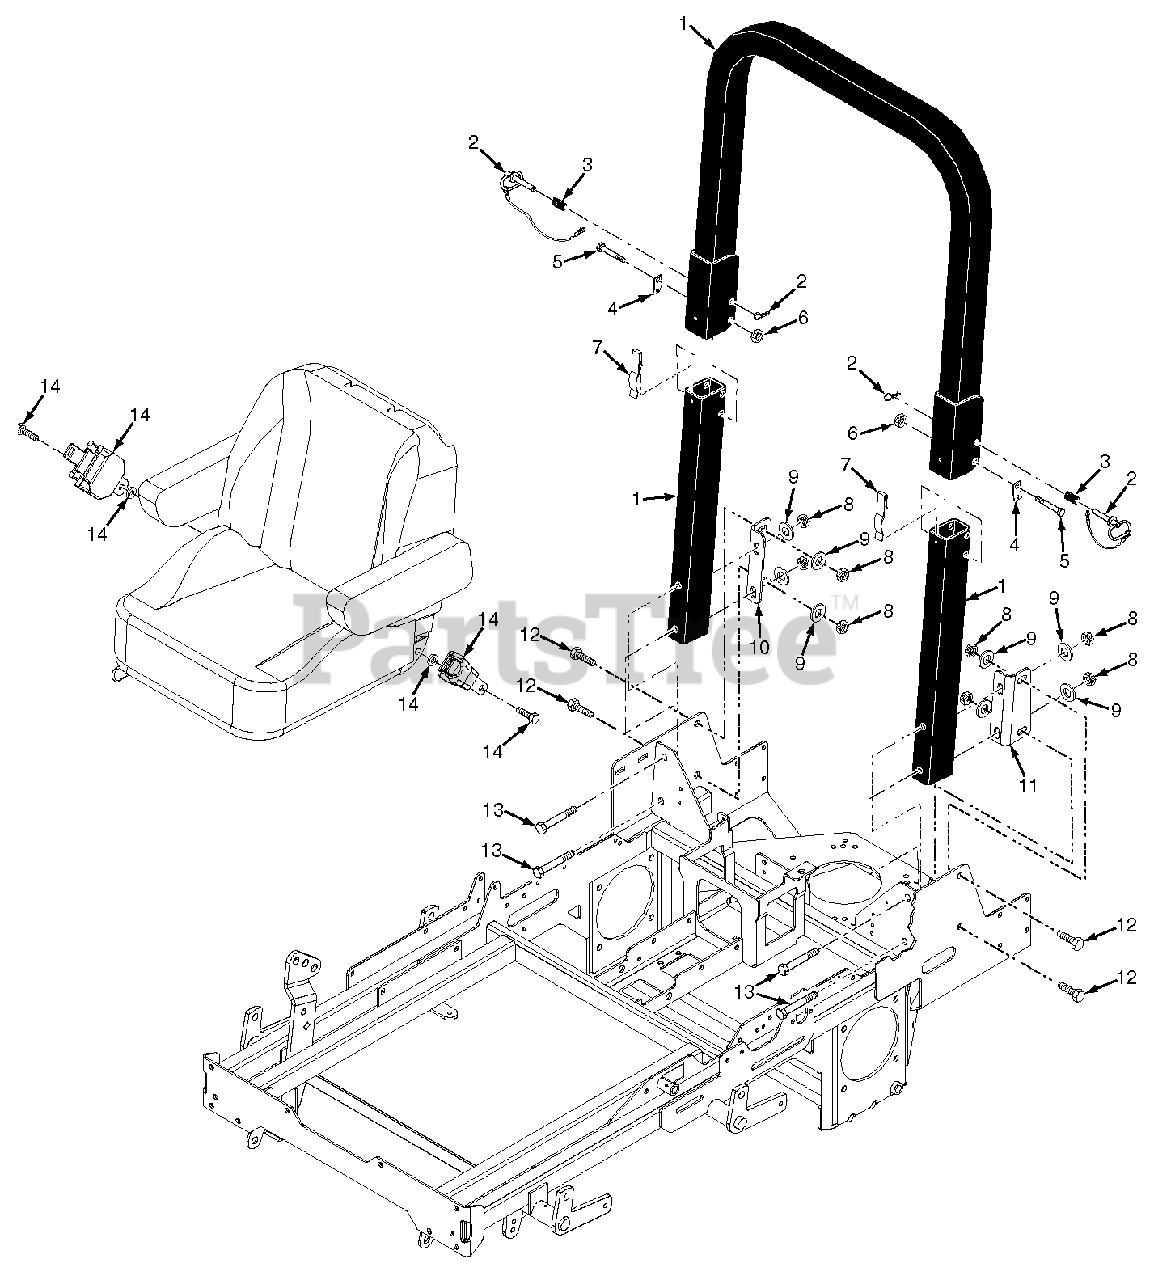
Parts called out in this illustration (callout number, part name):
1	ROPS, Foldable SCZ
2	Pin Assembly
3	Spring, ROPS
4	Clip, ROPS
5	Bolt, Hex Head 1/2-13 x 3-1/4"
6	Nut, Elastic Stop 1/2-13
7	Spring Clip, ROPS
8	Nut, Center Lock 1/2-13
9	Flatwasher, 1/2-.562 x 1.375 x .109
10	ROPS Mount, RH Rear
11	ROPS Mount, LH Rear
12	Bolt, Hex Head 1/2-13 x 1-1/4"
13	Bolt, Hex Head 1/2-13 x 4-1/4"
14	Seat Belt Kit, Retractable - SCZ
